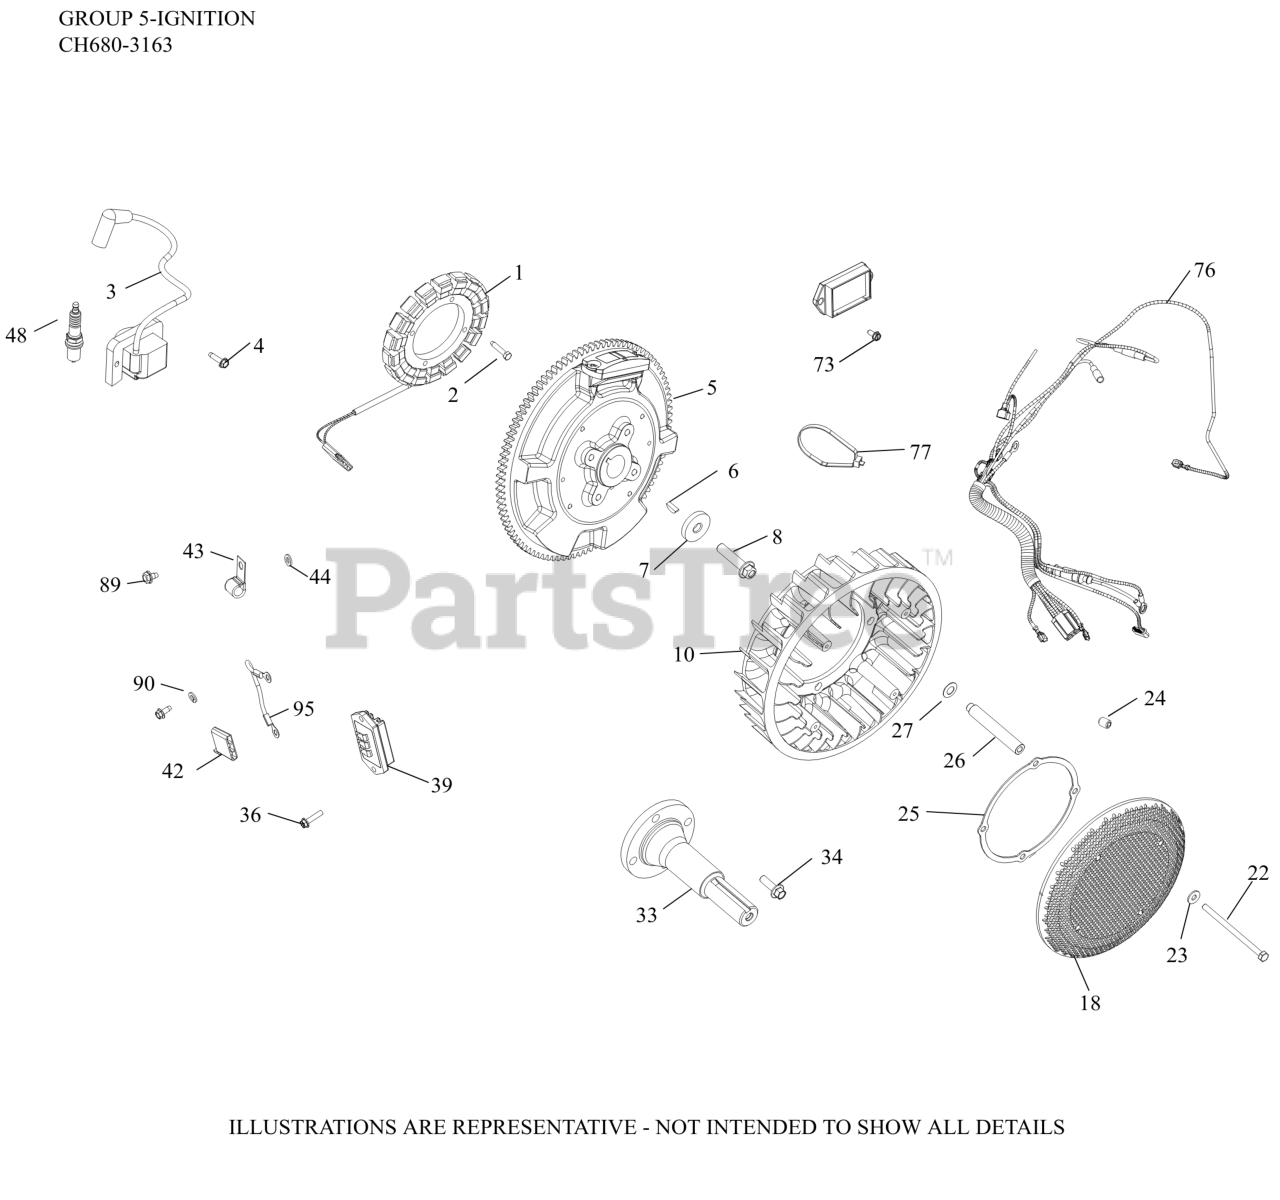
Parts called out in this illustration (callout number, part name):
1	KIT, 15 / 20 AMP STATOR
2	SCREW, THREAD FORMING
3	MODULE, EMC/RFI COMPLIANT
4	SCREW, THREAD FORMING
6	KEY, 3/16" X 5/8"
7	WASHER, FLAT 13/32"
8	SCREW, FLG M10X1.5X45-USE 25 086 361-S
10	FAN-USE 24 755 253-S
18	SCREEN, GRASS
22	SCREW, CAP M6X1.0X99.5
23	WASHER, FLAT 1/4" (O.D. 5/8")
24	SCREW, SKT SET #10-24X1/4"
25	RING, SUPPORT
27	WASHER, SPRING 10 MM
33	SHAFT, FRONT DRIVE
34	SCREW, FLG M8X1.25X25
36	SCREW, HEX FLANGE HI-LO
39	REGULATOR/RECT 12/15A (41 403 10-S)
42	CONNECTOR
43	CLIP, CABLE
44	WASHER, FLAT 1/4" (O.D. 1/2")
48	SPARK PLUG, RFI
73	SCREW, WSH HD TAP #8-18X1/2"
76	HARNESS, WIRING ASSEMBLY
89	SCREW, THREAD FORMING
90	WASHER, LOCK
